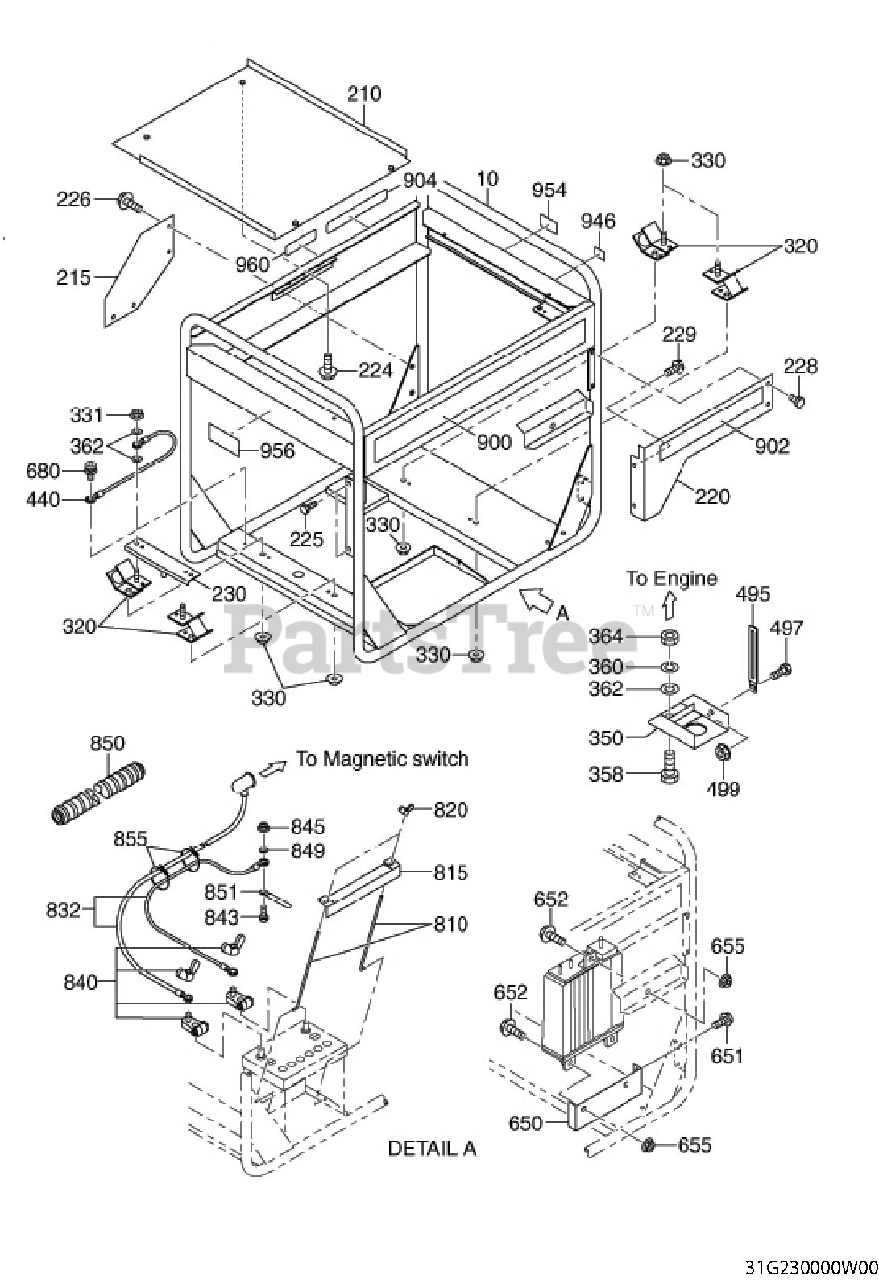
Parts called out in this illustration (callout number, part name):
10	PIPE FRAME CP
224	FLANGE BOLT
228	SCREW and WASHER AY
229	FLANGE BOLT
230	GENERATOR BASE
330	FLANGE NUT
358	BOLT
360	SPRING WASHER
362	WASHER
495	CLAMP
497	FLANGE BOLT
499	FLANGE NUT
650	BRACKET, CANISTER
652	FLANGE BOLT
655	FLANGE NUT
680	SCREW
815	BATTERY STAY CP
832	WIRE CABLE SET
840	BATTERY TERMINAL
843	BOLT AND WASHER AY
845	FLANGE NUT
849	WASHER
850	CORRUGATED TUBE
851	CLAMP
855	WIRE BAND
902	LABEL (RGV12100)
946	LABEL (FUEL STRAINER)
956	LABEL (HOT & GAS)
